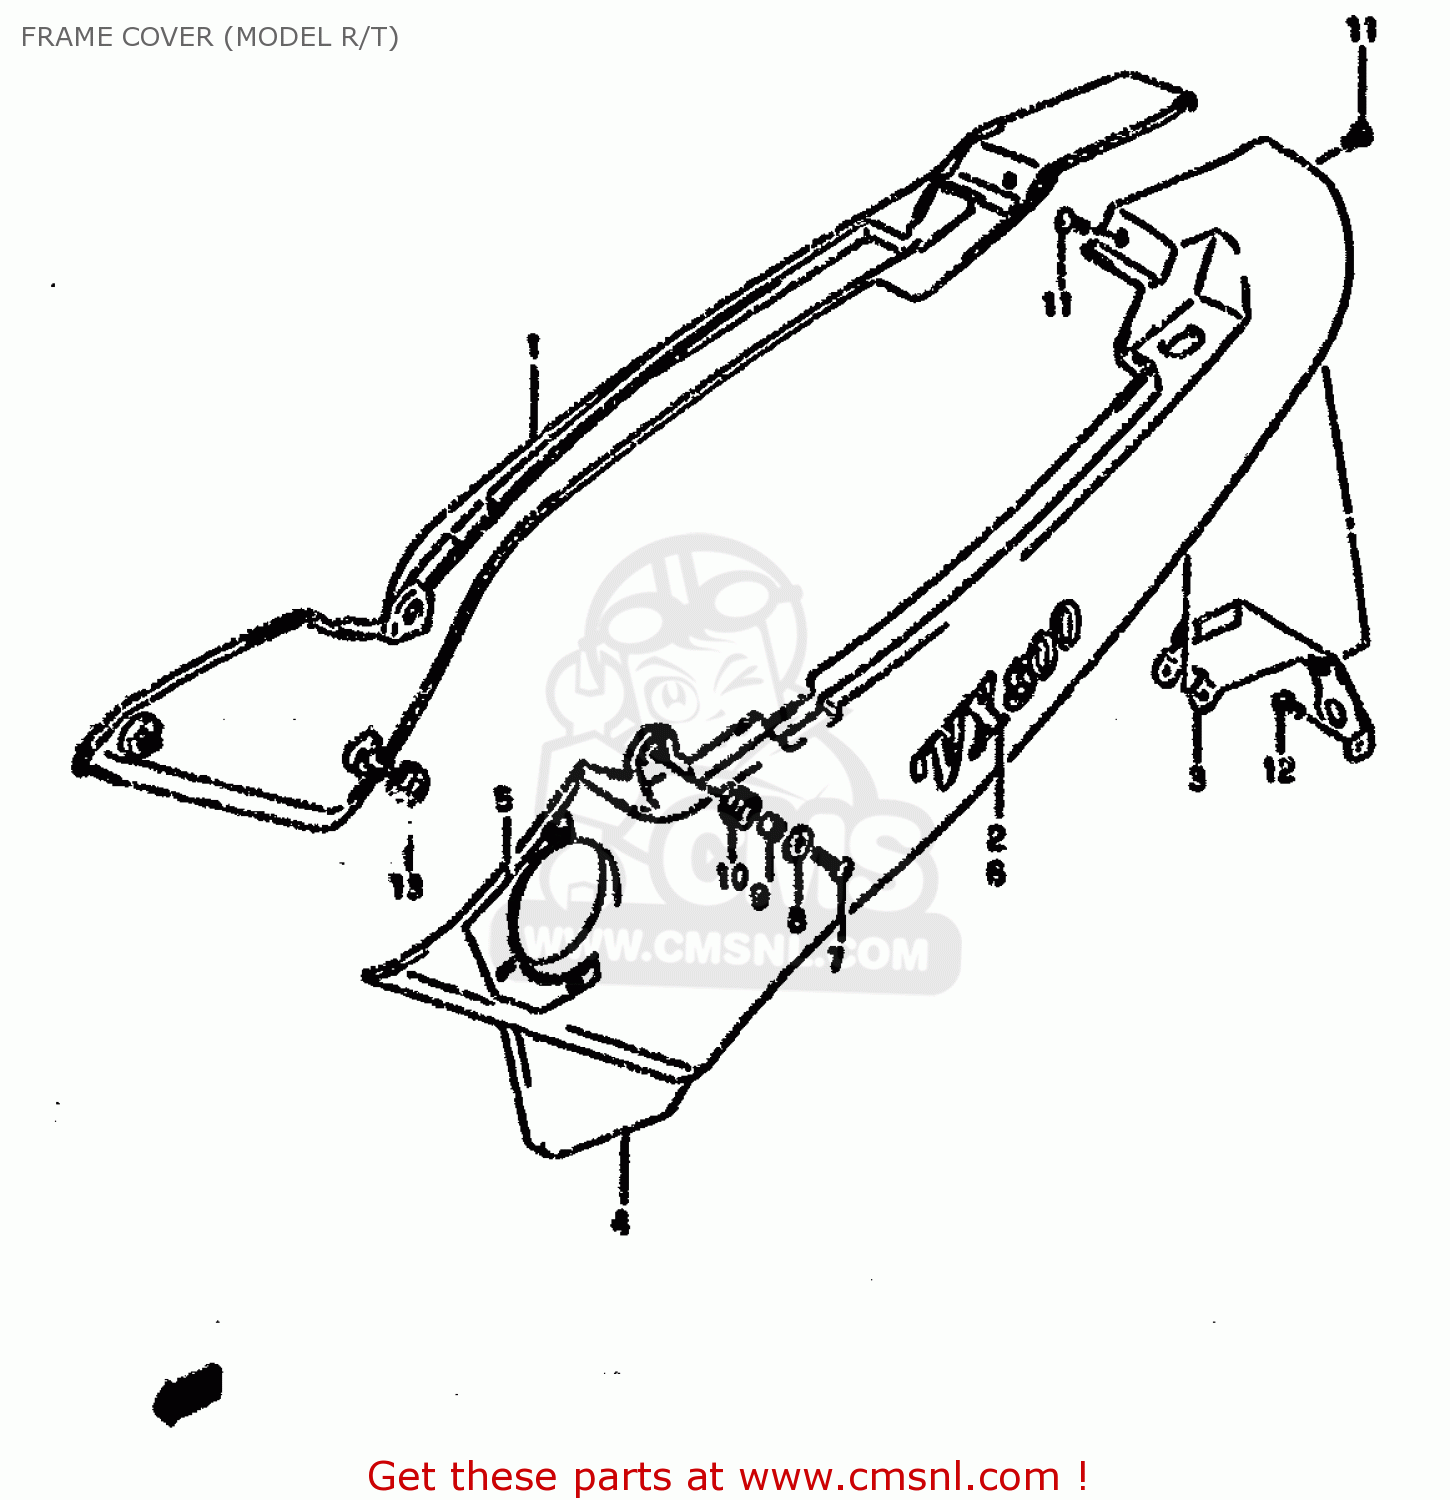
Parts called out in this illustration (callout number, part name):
1	COVER,FRAME,R
2	EMBLEM,FRAME COVER
3	BRACKET COMP,FRAME COVER
4	COVER,FRAME,L
5	LABEL (FUEL COCK)
6	EMBLEM,FRAME COVER
7	SCREW
8	WASHER(6.5X18X1)
9	COVER COMP,FRAME,LEFT
10	CUSHION
11	EMBLEM,FRAME COVER
12	SCREW
13	CUSHION
14	SPACER
15	CUSHION
16	SCREW
17	SCREW
18	CUSHION
